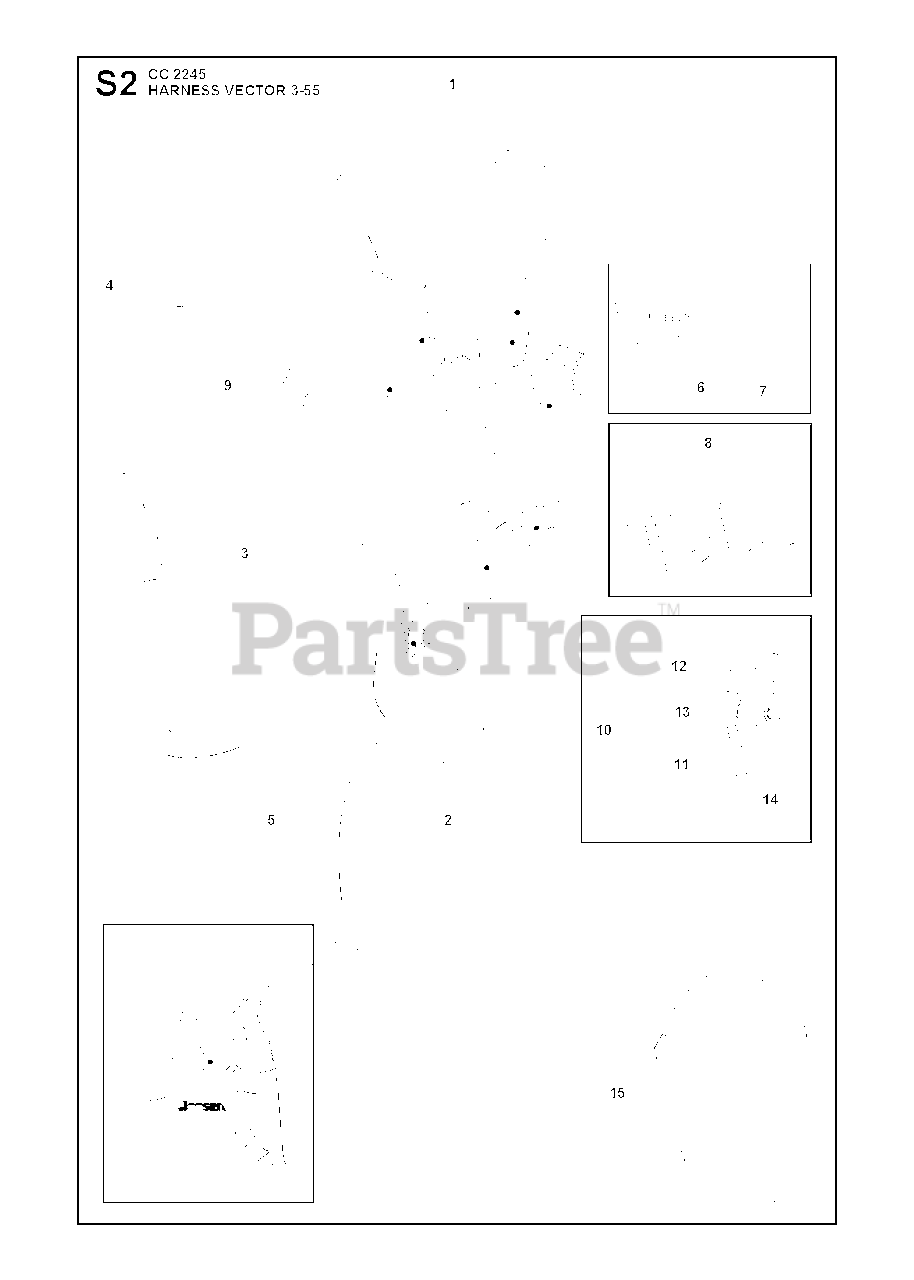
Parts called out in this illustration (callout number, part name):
1	HARNESS "VECTOR" 2-55
1	HARNESS COMPLETE
2	BAND
3	CLIP
4	BAND
5	HARNESS HOOK, COMPLETE
6	CATCH *
7	SPRING
8	HOOK
9	E-RING 5
10	RIVET
11	PROTECTOR
12	FRONT PIECE
13	FRONT PIECE
